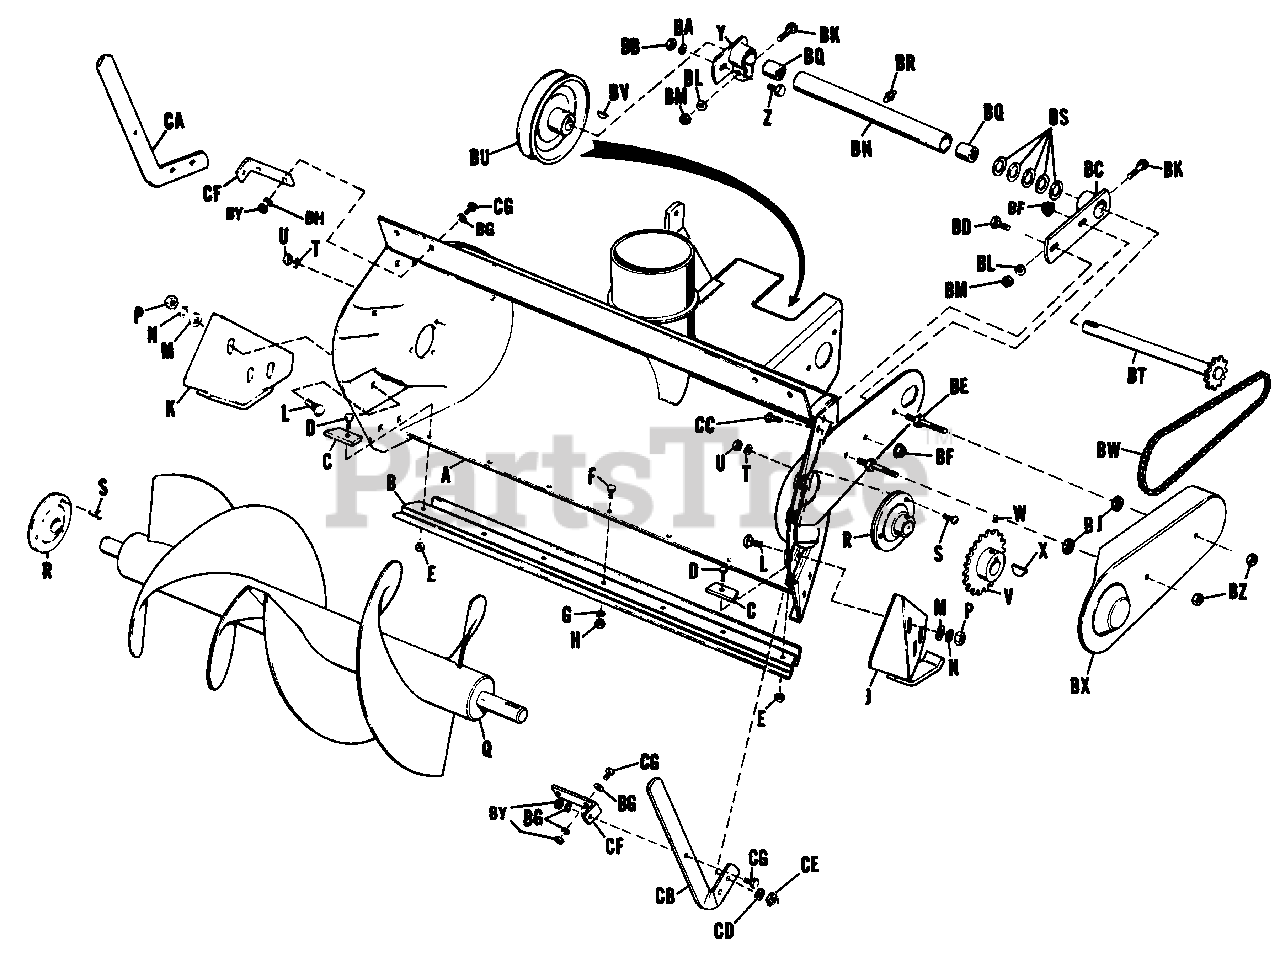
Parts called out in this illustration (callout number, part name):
A	Body Assembly
B	Body Scraper
C	Scraper Clamp
D	Hex Capscrew, 5/16"-18 x 7/8" lg.
E	Hex Lock Nut, Full, 5/16"-lg.
F	Hex Capscrew, 1/4"-20 x 5/8" lg.
G	Lock Washer, 1/4"
H	Hex Nut, Full, 1/4"-20
J	Shoe Assembly, Left Hand
K	Shoe Assembly, Right Hand
L	Carriage Bolt, 3/8"-16 x 3/4" lg.
M	Plain Washer, 3/8 "
N	Lock Washer, 3/8"
P	Hex Nut, Full, 3/8"-16
Q	Rotor Assembly
R	Ball Bearing
S	Hex Capscrew 5/16"-18 x 3/4" lg.
T	Lock Washer, 5/16"
U	Hex Nut, Full, 5/16"-18
V	Rotor Sprocket
W	Set Screw, Socket Hd., Cup Pt., 5/16"-18 x 5/16" lg.
Y	Clamp Support Assembly
Z	Hex Capscrew, 3/8"-16 x 1" lg.
BA	Lock Washer, 3/8"
BB	Hex Nut, Full, 3/8"-16
BC	Clamp Support Assembly
BD	Hex Capscrew, 3/8"-16 x 1" lg.
BF	Whizlock Nut 3/8-16
BG	Plain Washer, 5/16"
BH	Lock Washer, 5/16"
BJ	Hex Lock Nut, Full, 3/8"-16
BK	Hex Capscrew, 5/16"-18 x 1-1/2 lg.
BL	Lock Washer, 5/16"
BM	Hex Nut, Full, 5/16"-18
BN	Bearing Housing
BQ	Needle Bearing
BR	Grease Fitting #1641 Alemite
BT	Shaft Assembly
BV	Woodruff Key
BW	Chain, w/Conn. Link
BX	Chain Guard
BY	Hex Nut, Full, 5/16"-18
BZ	Whizlock Nut 3/8-16
CA	Drift Cutter, Right Hand
CB	Drift Cutter, Left Hand
CC	Hex Capscrew, 3/8"-16 x 3/4" lg.
CD	Lock Washer, 3/8 "
CE	Hex Nut, Full, 3/8"-16
CG	Hex Capscrew, 5/16"-18 x 3/4" lg.
